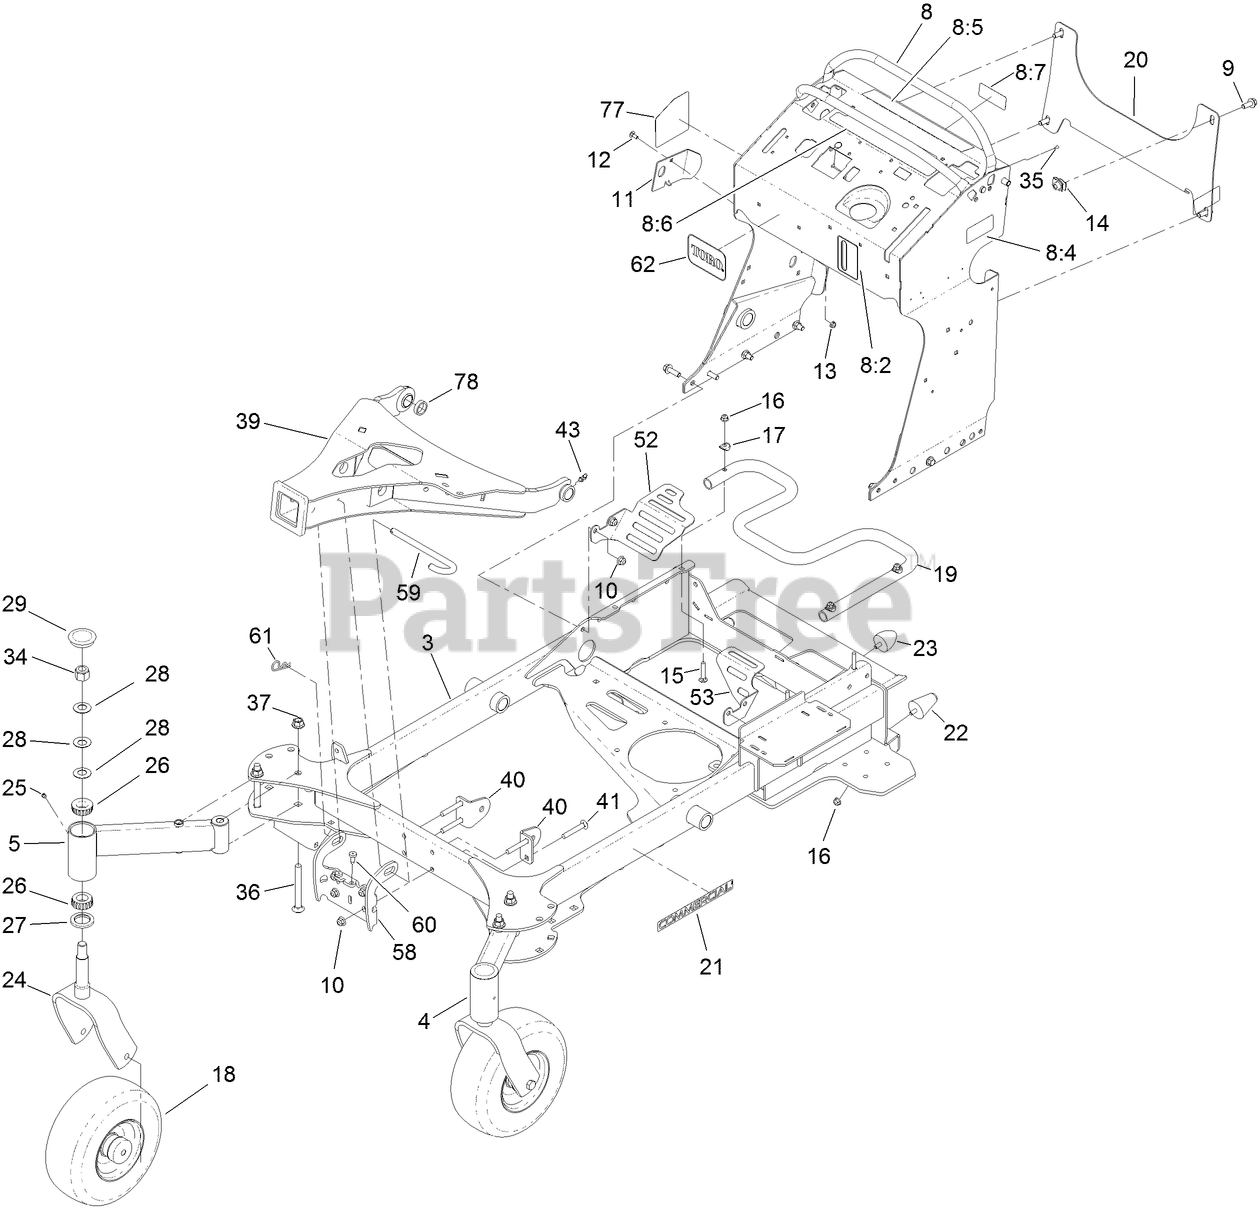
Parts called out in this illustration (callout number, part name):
4	TUBE-CASTOR, SHORT
5	TUBE-CASTOR, LONG
8	TOWER DECAL ASM
8:2	DECAL-LEVEL, OIL
8:4	DECAL-FILL, FUEL
8:6	DECAL-CONTROLS
8:7	DECAL-FUSE
9	SCREW-HHF
10	NUT-HF, NI
11	PLATE-STRIKER
12	SCREW-CARR
13	NUT-HF
14	NUT-TINNERMAN
15	BOLT-CAR
16	NUT-HF, NI
17	WASHER
18	WHEEL/TIRE AND BEARING ASM
19	TUBE-MOUNT, FUEL TANK
20	BRACKET-CROSS
21	DECAL-COMMERCIAL
22	BUMPER-RUBBER
23	BUMPER-RUBBER
24	FORK-CASTER
26	BEARING-ROLLER, TAPERED
27	SEAL-GREASE
28	WASHER-BELLVILLE
29	CAP-GREASE
34	NUT-LOCK, NI
35	RIVET-POP
36	SCREW-CARR
37	NUT-LOCK
40	BRACKET-CYLINDER
41	SCREW-CARR
43	FITTING-GREASE, 90 DEG
52	GUARD-FAN, RH
53	GUARD-FAN, LH
58	BRACKET-LOCK
59	PIN-HITCH
60	BUMPER-RUBBER
61	PIN-HAIR
62	DECAL-LOGO, TORO
77	DECAL SERVICE-MULTIFORCE
78	SPACER
